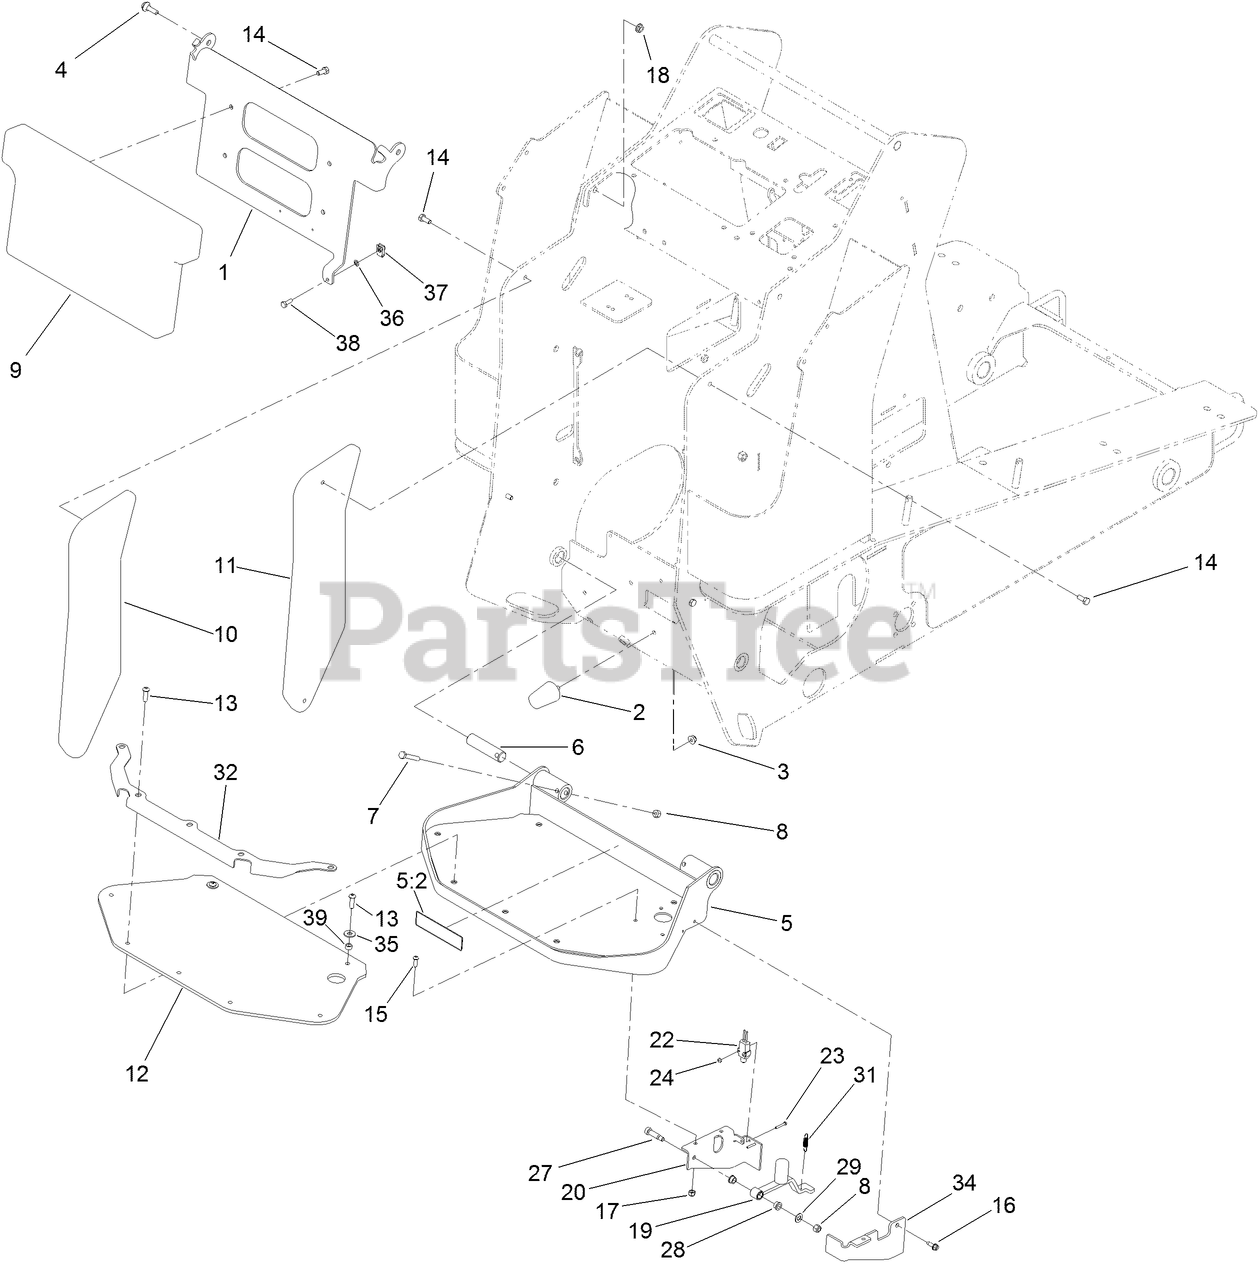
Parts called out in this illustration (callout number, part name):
1	HINGE-PAD
2	BUMPER
3	NUT-HF, NI
4	SCREW-SHOULDER
5	PLATFORM
5:2	DECAL-PARKING BRAKE
6	PIN-PIVOT
7	SCREW-HH
8	NUT-LOCK, NI
9	CUSHION-PAD
10	CUSHION-PAD
11	CUSHION-PAD
12	PAD-FOOT
13	SCREW-HSH
14	SCREW-HH
15	SCREW-HSBH
16	SCREW-HWH
17	NUT-LOCK, NI
18	NUT-HF
19	LEVER-SWITCH, AUX
20	BRACKET-SWITCH, LH
22	SWITCH
23	SCREW
24	NUT-HEX
27	BOLT-SHOULDER
28	BUSHING-FLANGED
29	WASHER-FLAT
31	SPRING
32	PLATE-CLAMP
34	BRACKET-SWITCH, RH
35	WASHER-FLAT
36	NUT-RETAINING
38	SCREW-HH
39	SPACER-PIVOT, TILT
